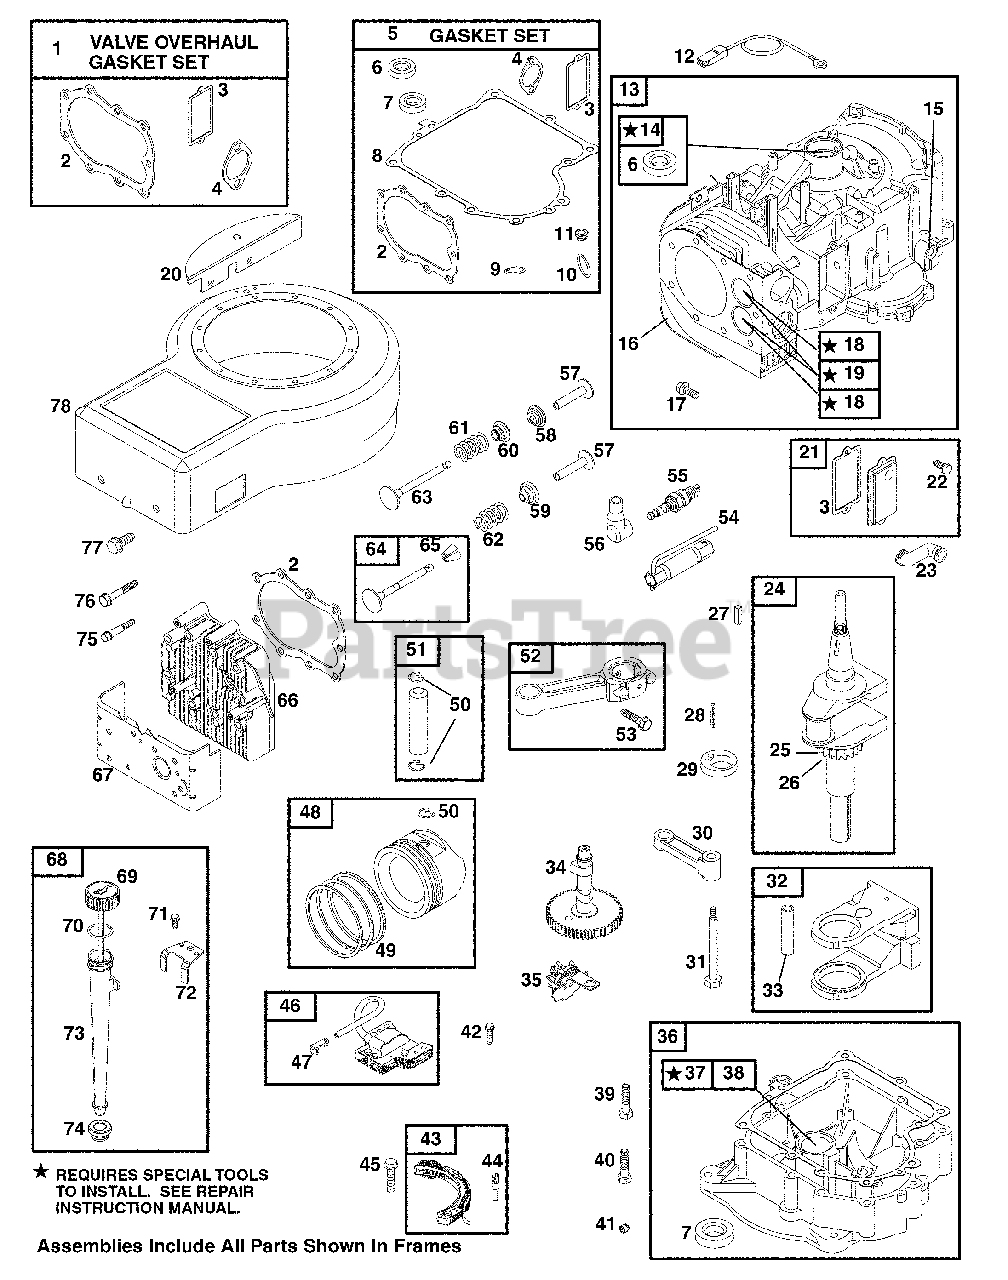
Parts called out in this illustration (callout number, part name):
1	Valve Overhaul Gasket Set
2	Cylinder Head Gasket
3	Breather Gasket
4	Intake Gasket
5	Gasket Set-Engine Overhaul
6	Oil Seal
7	Oil Seal
8	Crankcase Gasket (.015" Thick)
9	O-Ring Seal
10	O-Ring Seal
11	Dipstick Tube Seal
13	Cylinder Assembly
14	Bushing/Seal Kit
15	Bushing-Gov. Crank
16	Shield-Cylinder
17	Screw
18	Seat-Valve
19	Bushing-Guide (Exhaust Valve)
20	Flywheel Guard
21	Breather Assembly
22	Screw
23	Breather Tube
24	Crankshaft
25	Gear-Timing
26	Key-Timing
27	Flywheel Key
28	Pin-Retainer
30	Link-Counterweight
31	Screw (Counterweight)
32	Counterweight
33	Pin-Counterweight
35	Governor / Oil Slinger
36	Engine Sump
37	Bushing / Seal Kit (PTO Side)
38	Oil Seal (PTO Side)
39	Screw
40	Screw
41	Oil Drain Plug
42	Screw
43	Alternator
44	Wire-Alternator
45	Screw
46	Armature-Magneto
47	Terminal-Cable
48	Piston Assembly (Standard)
49	Ring Set (Standard)
50	Piston Pin Lock
51	Piston Pin (Standard)
52	Connecting Rod
53	Screw
54	Wrench-Sparkplug
56	Boot-Sparkplug
57	Valve Tappet
58	Valve Retainer
59	Valve Retainer
60	Seal-Valve
61	Valve Spring (Exhaust)
62	Valve Spring (Intake)
63	Intake Valve
64	Exhaust Valve
65	Valve Keeper
66	Cylinder Head
67	Cover-Cylinder Head
68	Dipstick/Tube Assembly
70	O-Ring Seal
71	Screw
72	Bracket-Oil Fill
73	Dipstick Tube
74	Dipstick Tube Seal
75	Screw
76	Screw (3" Long)
77	Screw
78	Housing-Blower
